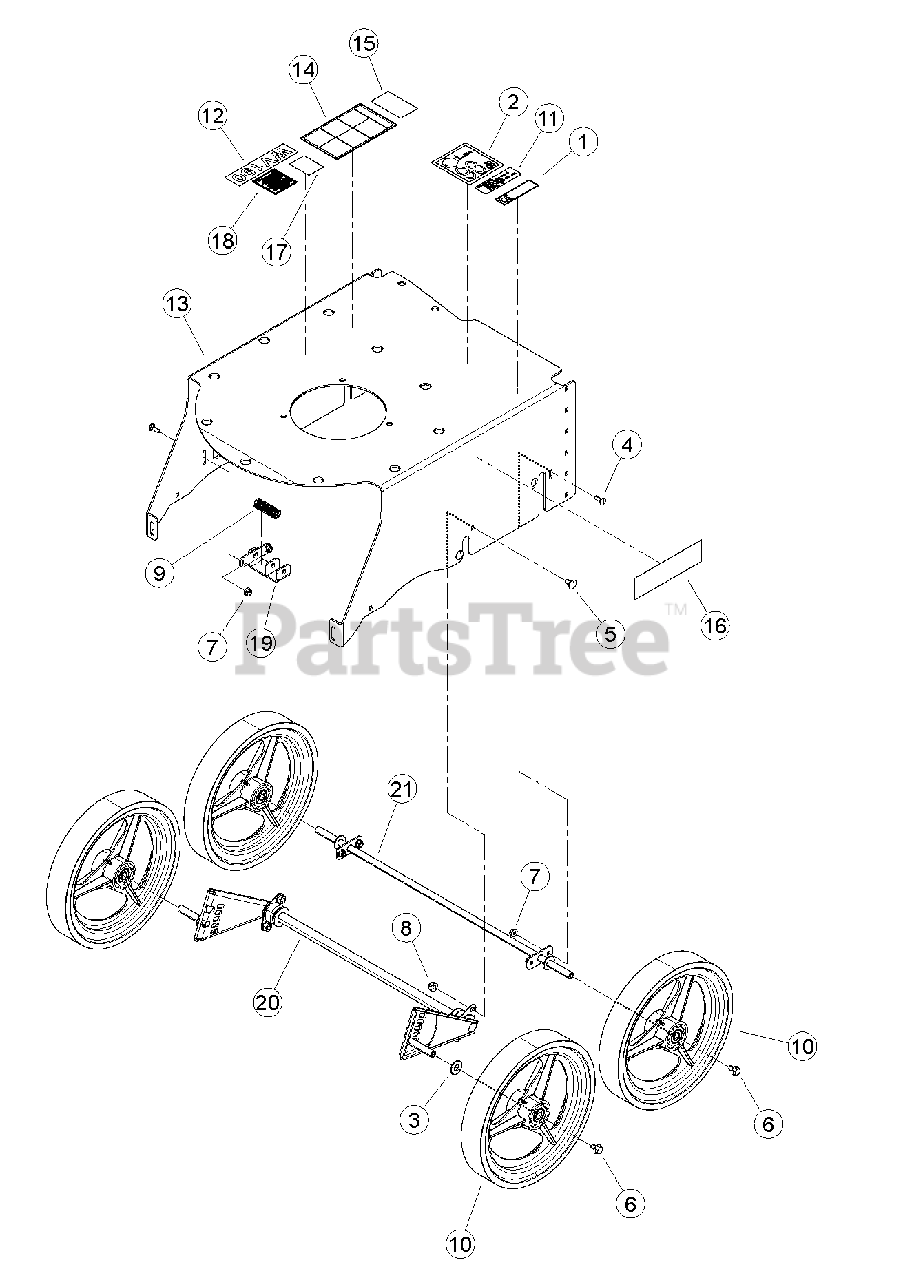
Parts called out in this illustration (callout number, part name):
1	DECAL, 6HP PUSH BEARVAC INFORMATION (WV190 ONLY)
2	DECAL, 98 DB (WV190 ONLY)
3	WASHER, 1/2 SAE FLAT
4	BOLT, 1/4 X 3/4 GR5 CRG ZP
5	BOLT, 5/16 X 5/8 GR5 CRG ZP
6	BOLT, 5/16-18 X 1/2 G5 HH SERRATED FLANGE
7	NUT, 1/4-20 NYLOCK FLANGE
8	NUT, 5/16-18 NYLOCK FLANGE
9	SPRING, LC-072J06S COMPRESSION
10	WHEEL ASSEMBLY, BEARVAC PUSH
11	DECAL, ATLANTIC BRIDGE LTD INFO (WV190 ONLY)
12	DECAL, MODEL WV190
12	DECAL, MODEL WV160
13	ASSEMBLY, PUSH VAC HOUSING W/ DECALS
14	DECAL, OPERATING INSTRUCTIONS ISO
15	DECAL, DANGER
16	DECAL, ECHO BEARCAT 6.82 X 1.90
17	DECAL, ECHO BEARCAT QR CODE
18	DECAL, SPARK ARRESTOR
19	WELDMENT, BEARVAC HEIGHT ADJ.
20	WELDMENT, AXLE PIVOT
21	WELDMENT, AXLE BEARVAC PUSH
